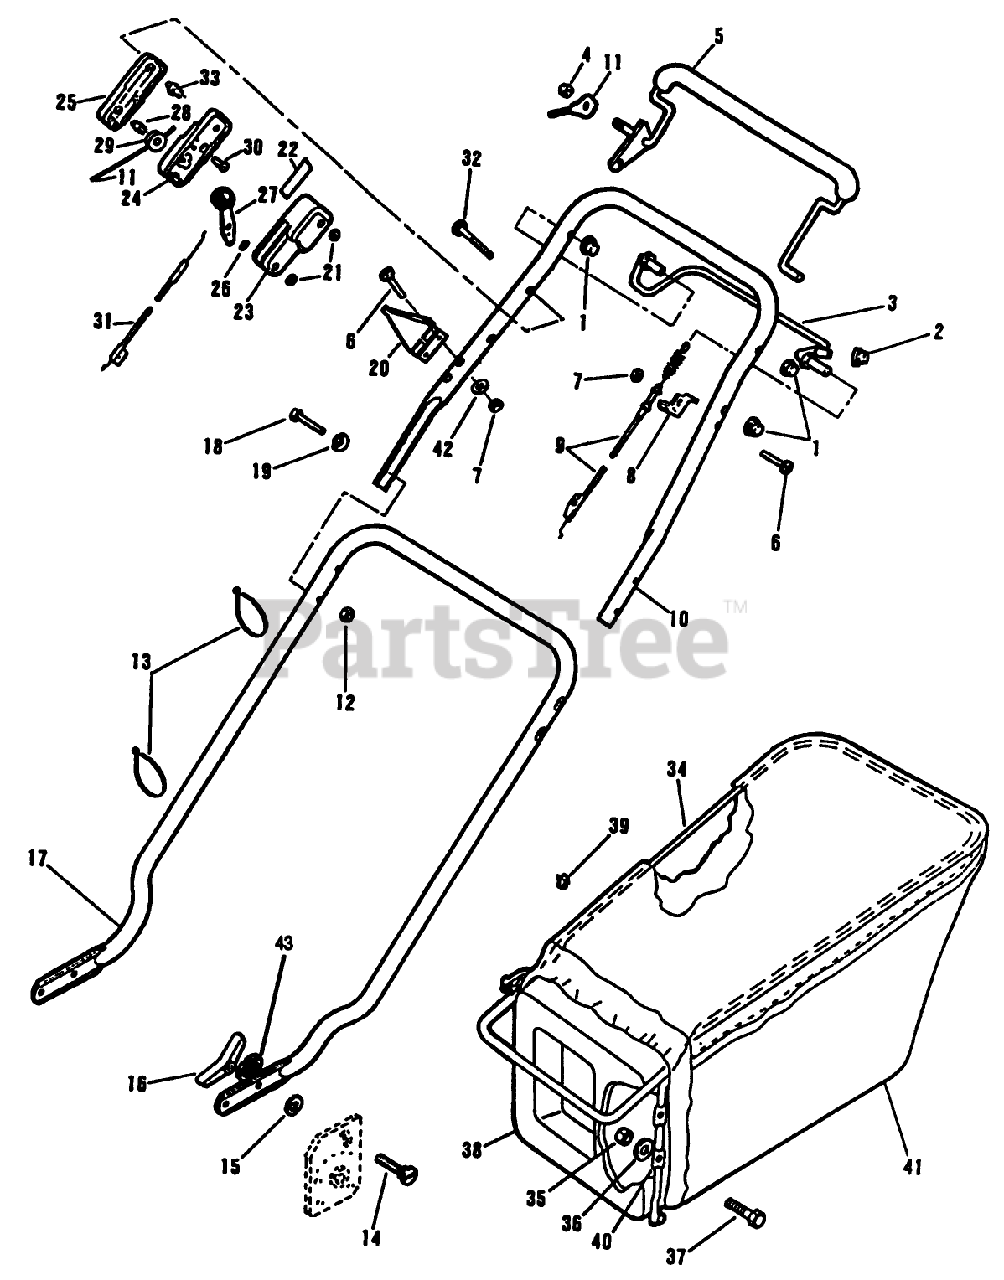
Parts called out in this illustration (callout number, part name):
2	Palnut-Cable to Bail
3	Self-propelled Bail
4	NUT ACORN
5	CONTROL LEVER ARG
7	LOCKNUT E
8	ANCHOR C'DUIT TRO
9	Self-propelled Bail
10	Top Handle Section
11	CONTROL CABLE
12	NUT-LOCK F
13	TIE-CABLE
14	Bolt-Handle to Handle Bracket
16	NUT-WING
17	LOWER HANDLE *G
18	Screw-Handle to Handle
19	WASHER-CURVED
21	Spacer
22	Decal-Throttle Control
25	OUTER CONTROL CASE
26	WASHER-SPRING
27	LEVER&KNOB AY WES
28	PIN SKF
29	PULLEY PL
30	SCREW
31	T/CABLE WESCON
32	SCREW
33	COLUMN
34	HANGER BAG TROX
35	LOCKNUT E
36	WASHER
38	BAG ADAPTOR PL
39	S CLIP ARDEN
40	LATCH BAR AY ARGO
42	WASHER
